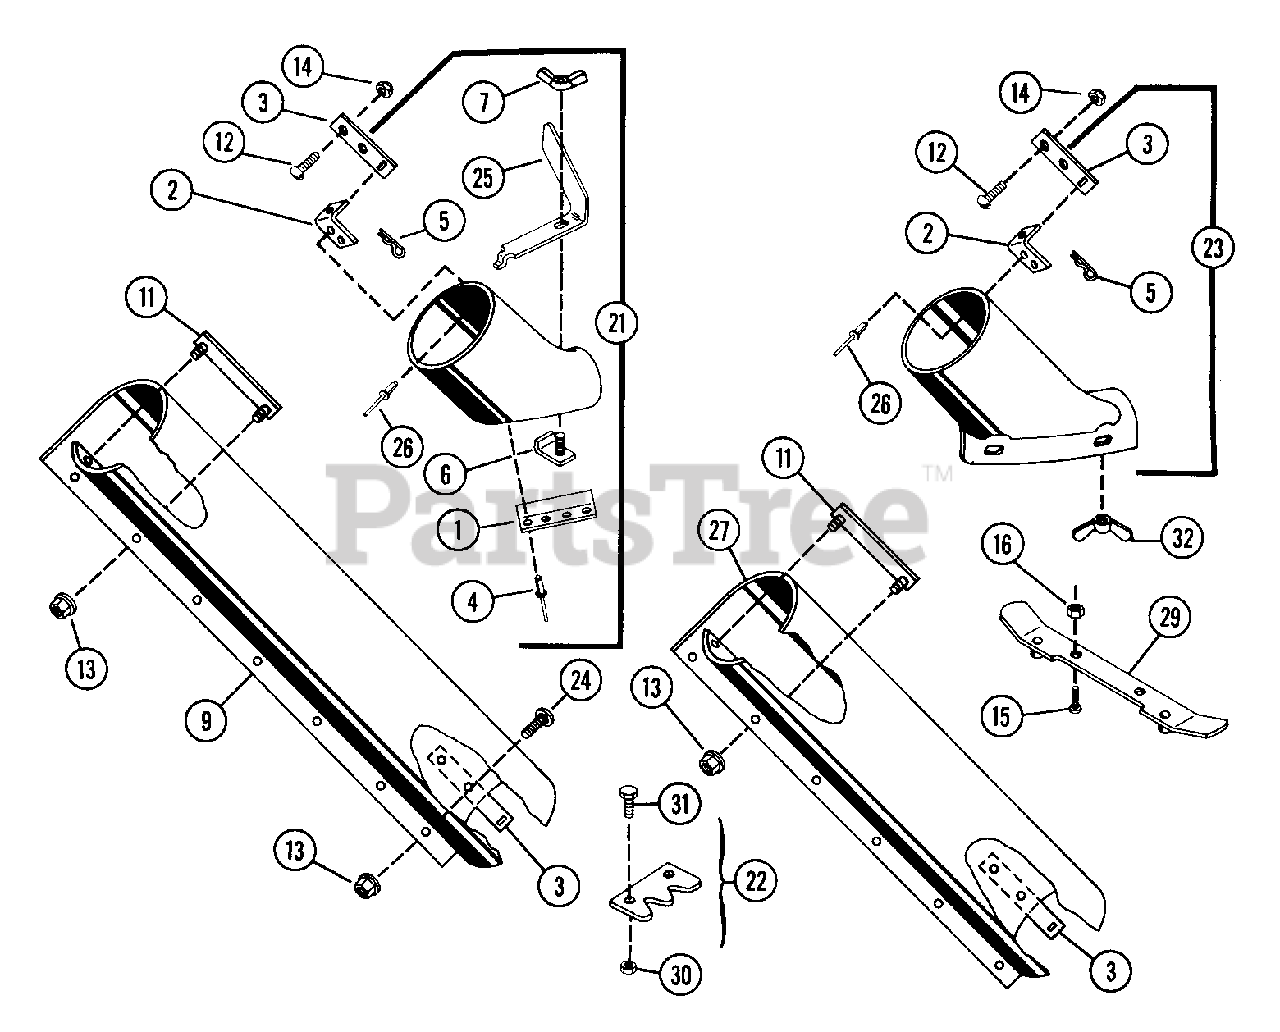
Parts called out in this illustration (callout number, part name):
1	EXTENSION CHUTE
2	RETAINER
3	STRAP
4	RVT .187X.343 TR ST PL
5	PIN-HAIR INT .09X.188 PL
6	CLIP CONE
7	NUT-WING W/INSERT .312 - 18
9	26 IN & 30 IN TUBE BLANK
12	SCR-MCH 10-24X.38 SLTOR PAN PL
13	NUT-LK-FLG .250-20 PL
14	NUT-LK TOP 10-24 PL
15	BLT-RDHDSQNK .25-20X1.00 GR5
21	BOOT ASSEMBLY
22	SERVICE VANE PACKAGE
24	BLT-RDHDSQNK .25-20X.50 SHT PL
25	BRACKET
26	RVT-TBLR .187X.375 OH ST PL
30	NUT-LK TOP .312-24 PL GR C
31	BLT-HEX .31-24X.75 GR8
